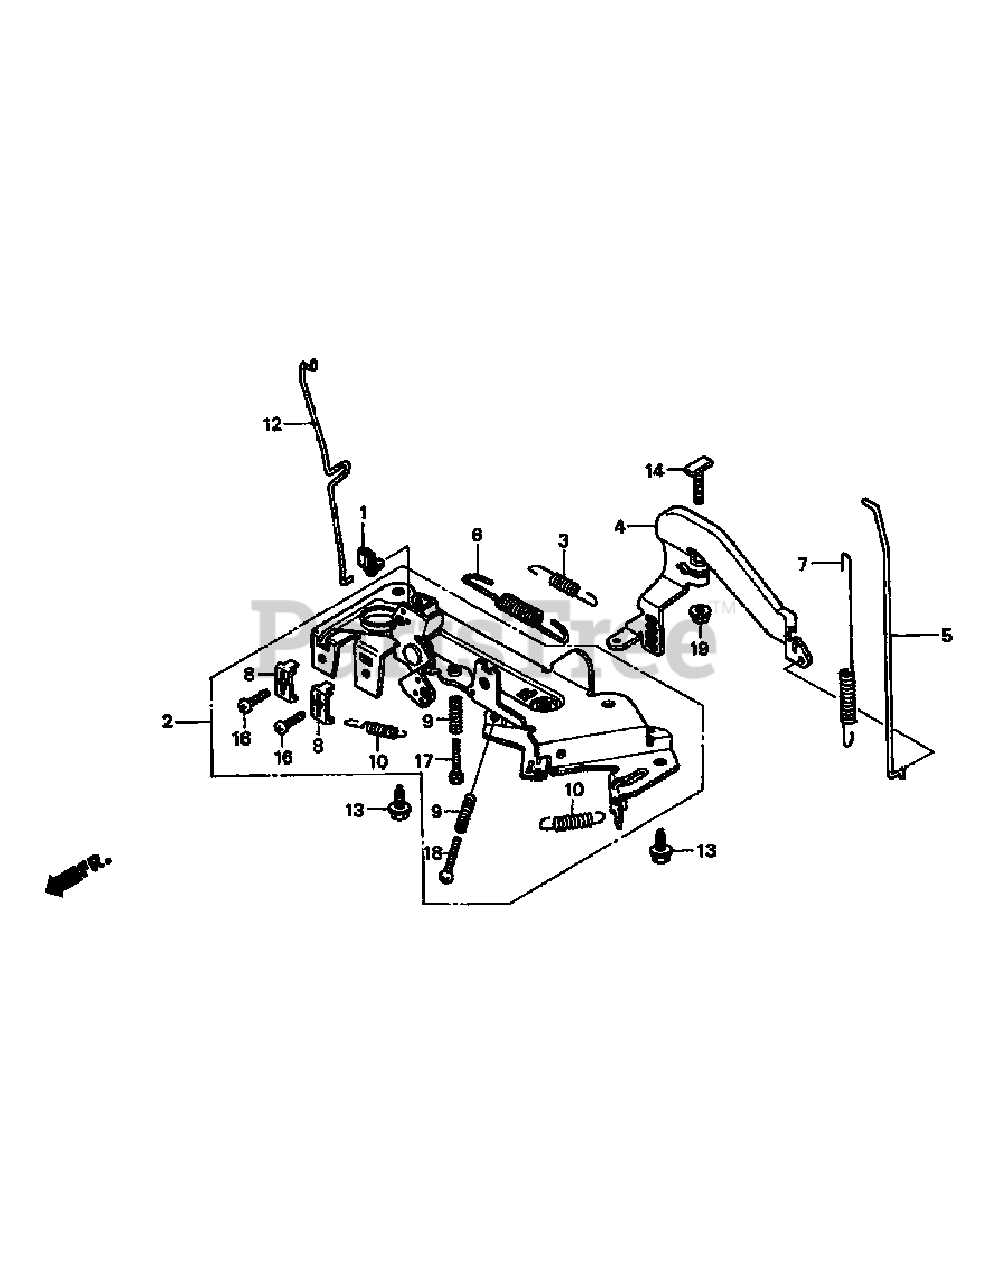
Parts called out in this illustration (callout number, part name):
2	Control Assy.
3	Starter Spring
4	Governor Arm
5	Governor Rod
6	Governor Spring
7	Throttle Return Spring
8	Cable Holder
9	Control Adusting Spring
10	Cable Return Spring
12	Choke Control Rod
13	Flange Bolt (6x14)
14	Governor Arm Bolt
16	Slot Bolt (5x16)
17	Slot Bolt (5x25)
18	Pan Screw (5x25)
19	Flange Nut (6mm)
